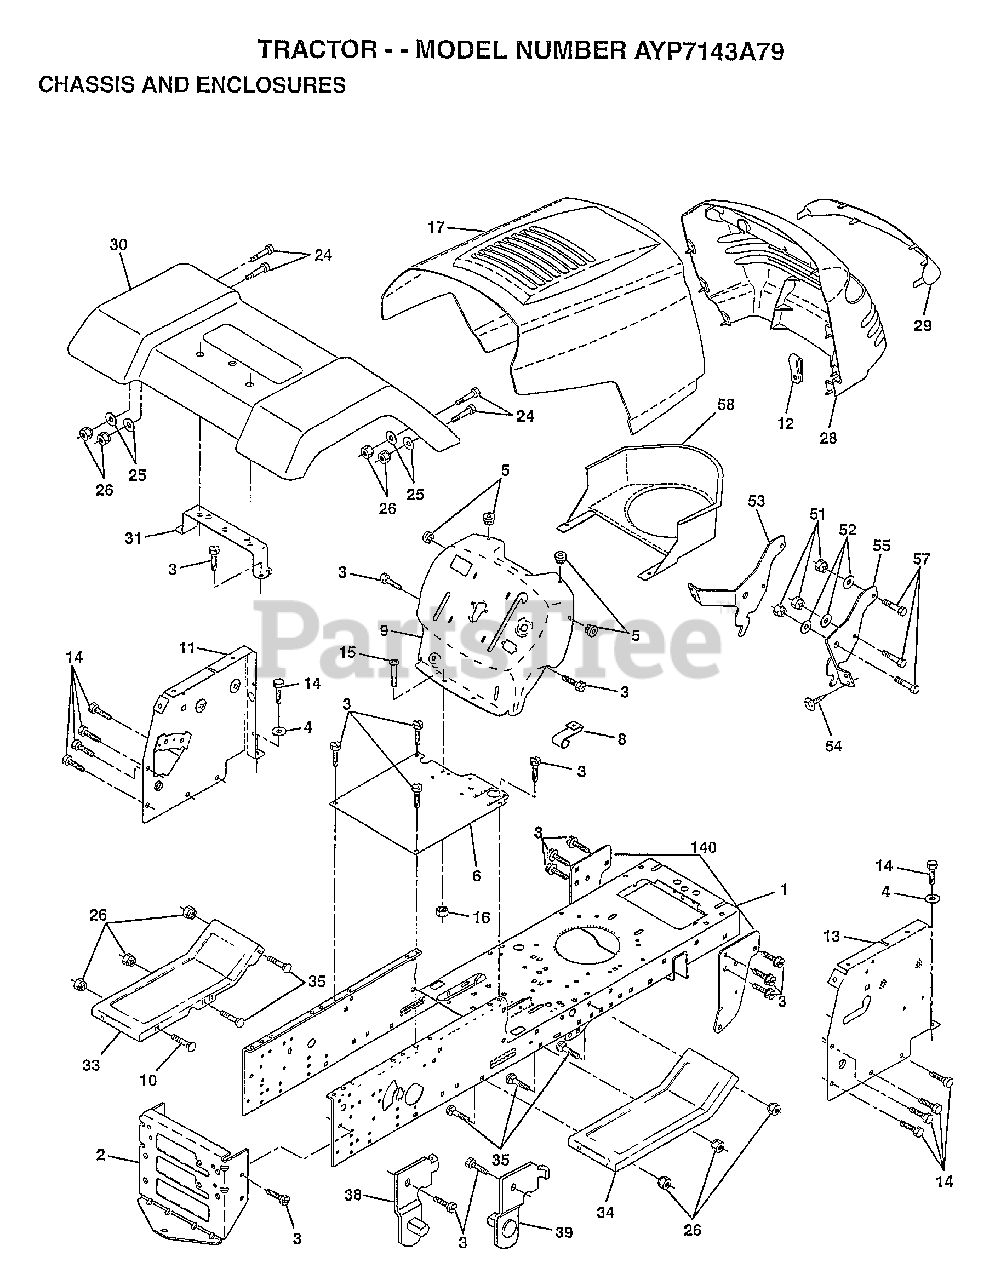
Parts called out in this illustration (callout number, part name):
1	CHASSIS ASM
3	SCREW
4	WASHER
5	BUMPER-HOOD/DASH
6	SADDLE-SILKSCREEN
8	"CLIP,INSULATOR"
9	DASH.SILKSCREENED
11	"PANEL-DASH,LH"
12	CLIP.TINNERMAN
14	SCREW LT
15	SCREW
24	BOLT
25	WASHER
26	NUT
28	GRILLE-MS428
29	LENS GRILLE
30	FENDER
31	BRKT FENDER
33	FOOTREST LH
34	FOOTREST RH
35	BOLT
38	BRACKET ASM LH
39	BRACKET ASM RH
51	NUT
52	WASHER
53	BRACKET.GRILLE.LH
55	BRACKET.GRILLE.RH
58	AIR DUCT
140	BRKT SUSPENSION
